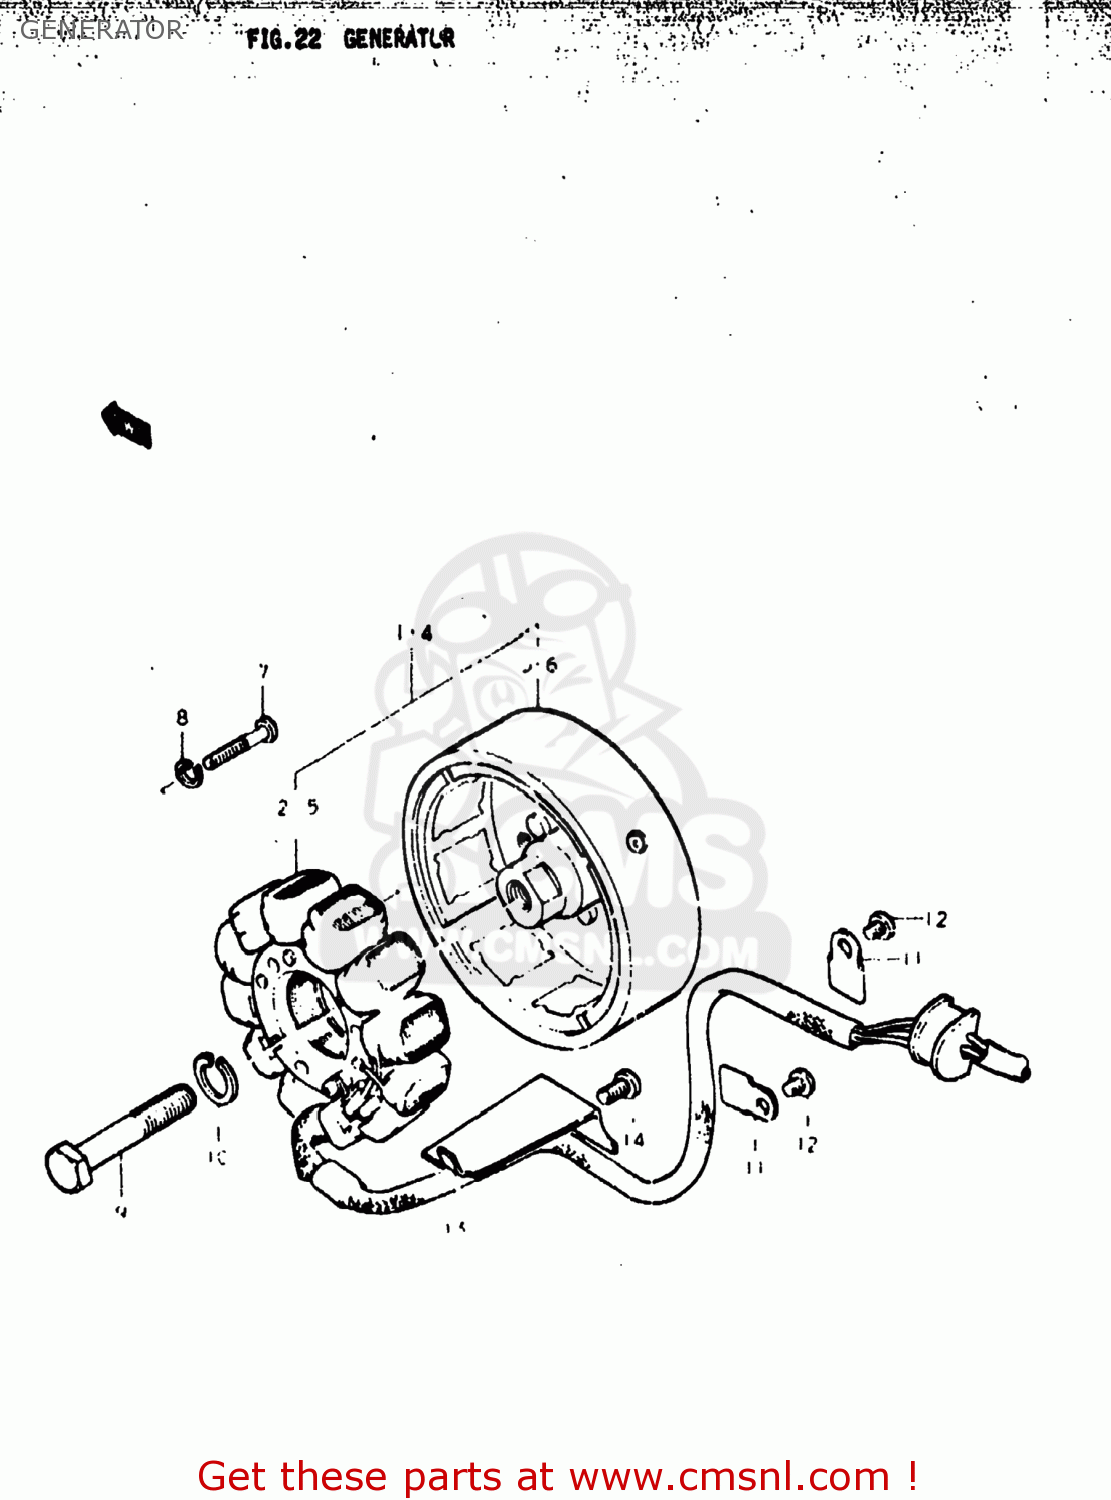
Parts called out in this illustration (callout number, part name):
1	GENERATOR ASSEMBLY
2	STATOR ASSEMBLY
3	ROTOR ASSEMBLY
4	GENERATOR ASSEMBLY
5	STATOR ASSEMBLY
6	ROTOR ASSEMBLY
7	SCREW
8	LOCK WASHER
9	BOLT
10	WASHER,LOCK 12
11	CLAMP,GENERATOR LEAD WIRE
12	SCREW
13	CLAMP,GENERATOR LEAD WIRE
14	SCREW
